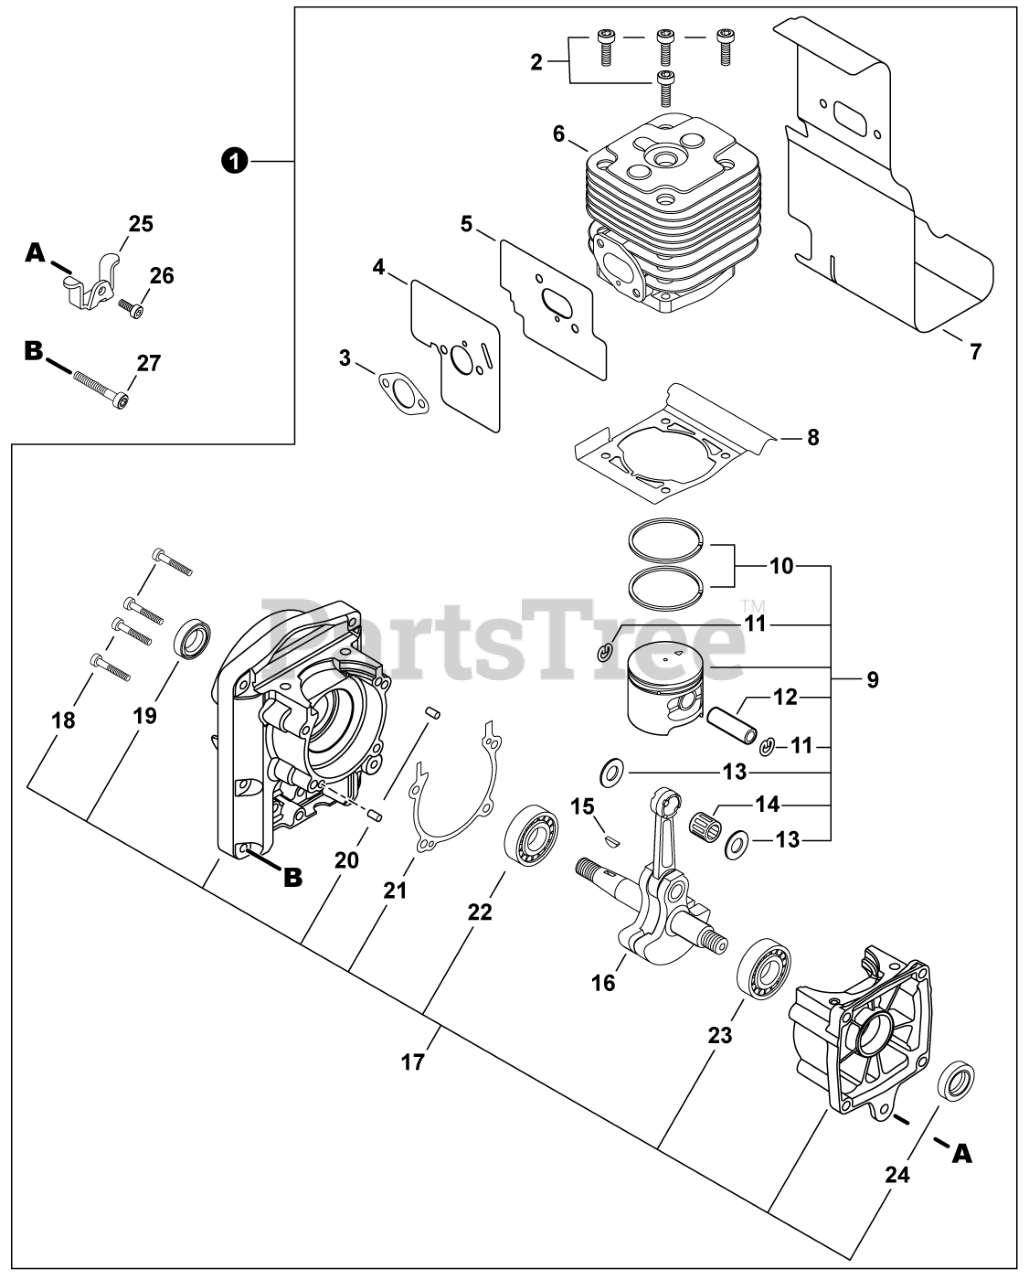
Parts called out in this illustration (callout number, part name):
1	SHORT BLOCK
2	BOLT, TORX 5x20
3	GASKET, INTAKE
4	GASKET, INTAKE
5	HEAT SHIELD, INTAKE
6	CYLINDER
7	HEAT SHIELD, EXHAUST
8	GASKET, CYLINDER
9	PISTON KIT
10	RING, PISTON
11	RING, SNAP 10
12	PIN, PISTON 10
13	WASHER, THRUST 10
14	BEARING, NEEDLE 10
15	KEY, WOODRUFF 3x14
16	CRANKSHAFT
17	CRANKCASE KIT
18	BOLT, TORX 5x30
19	SEAL, OIL
20	PIN, LOCATING 4x8
21	GASKET, CRANKCASE
22	BEARING, BALL 6302 C3
23	BEARING, BALL 6202
24	SEAL, OIL 15
25	CUSHION 5
26	BOLT, TORX 5x12
27	BOLT, TORX 5x30
